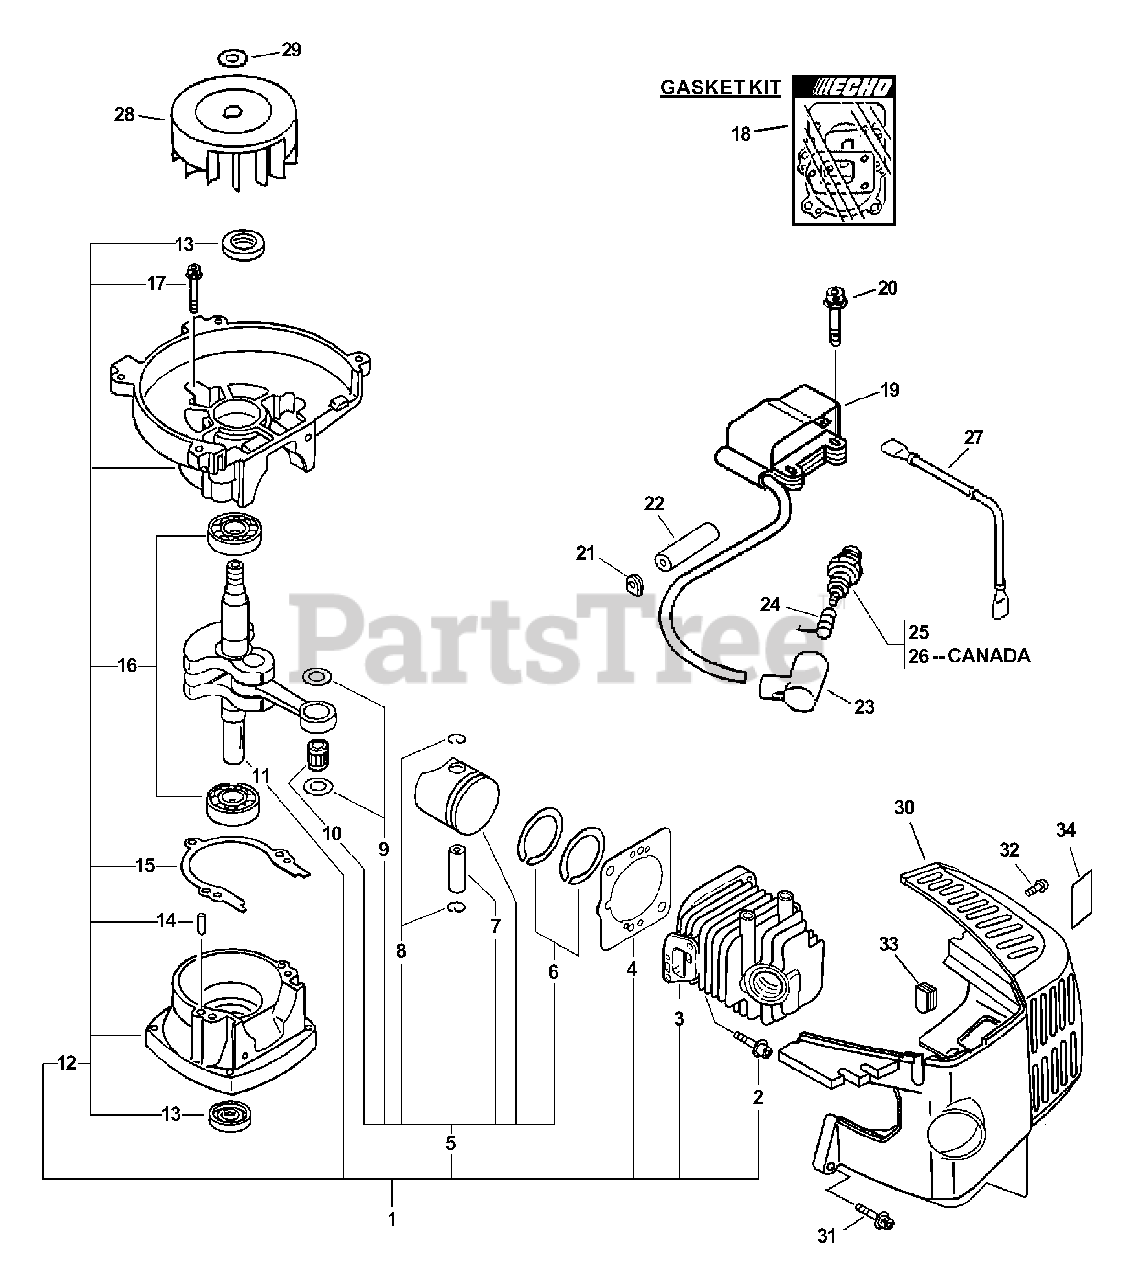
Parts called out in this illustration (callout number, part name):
1	SHORT BLOCK
2	BOLT 5×22
3	CYLINDER
4	GASKET, CYLINDER
5	PISTON KIT
6	RING, PISTON
7	PIN, PISTON 8
8	RING, SNAP
9	WASHER, THRUST
10	BEARING, NEEDLE
11	CRANKSHAFT ASSY
12	CRANKCASE KIT
13	SEAL, OIL 12
14	PIN, LOCATING 4
15	GASKET, CRANKCASE
16	BEARING, BALL - 6201 C3
17	BOLT 5×28
18	GASKET KIT
19	COIL, IGNITION
20	BOLT 4×20
22	TUBE, INSULATOR
23	CAP, SPARK PLUG
24	TERMINAL, SPARK PLUG
25	SPARK PLUG - BPM8Y
26	SPARK PLUG - BPMR8Y
27	LEAD - IGNITION
28	FLYWHEEL
29	WASHER 8.5×16×1.2
30	COVER, ENGINE
31	SCREW 4×22
32	BOLT 4×8
33	PLUG
34	LABEL, CAUTION - HOT
